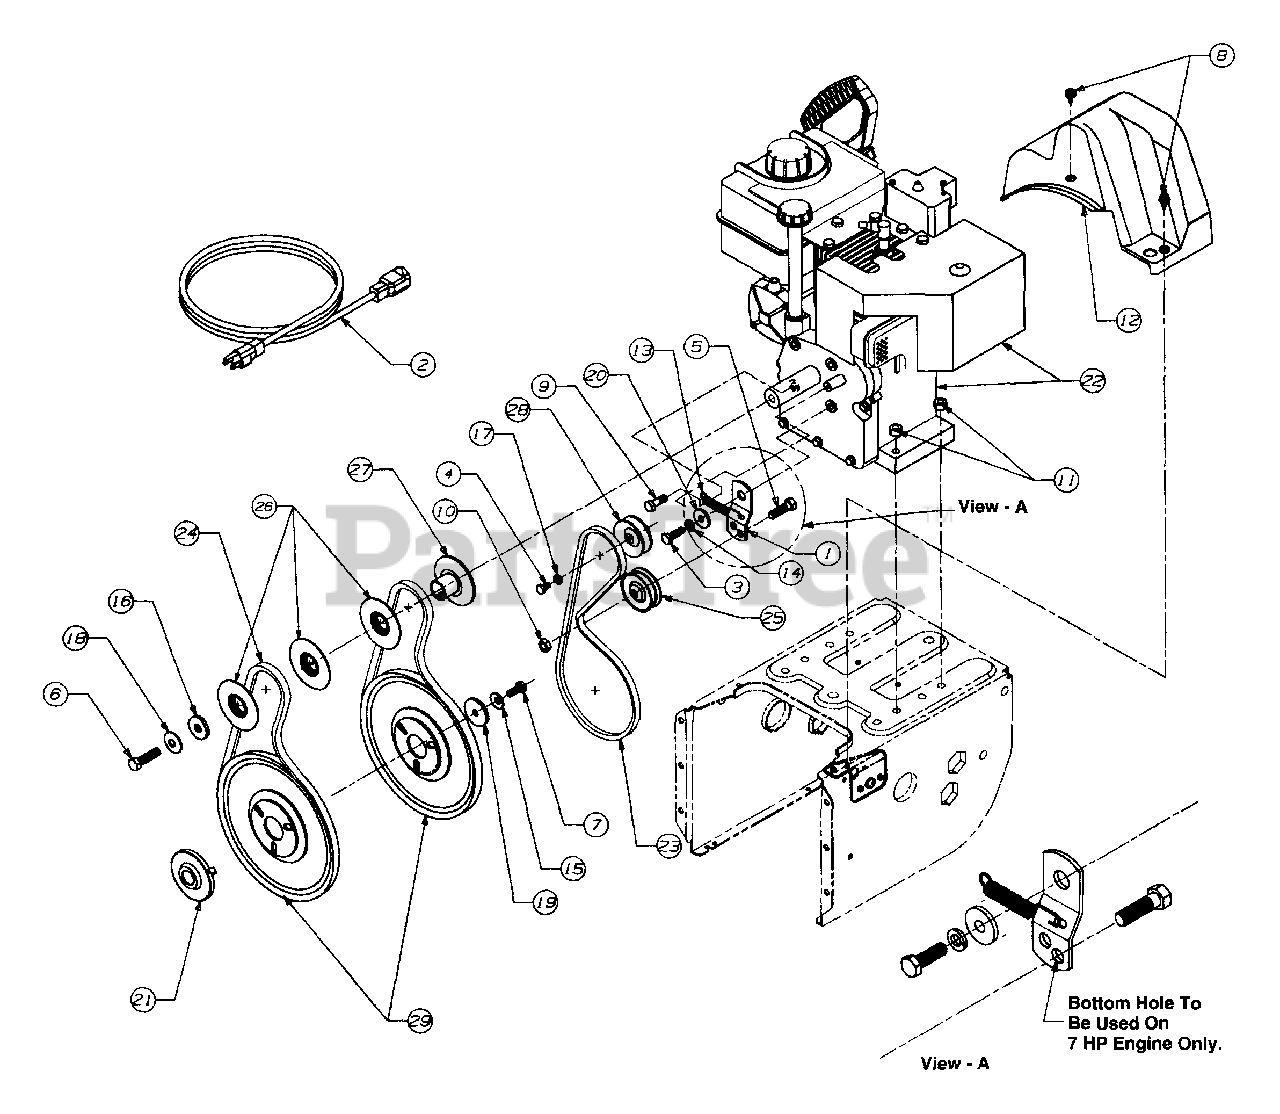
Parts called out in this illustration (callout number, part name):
3	Screw, Hex
4	Hex Screw
5	Screw, Hex
6	Hex Screw
7	Screw, Hex
8	Hex Screw
9	Screw, Hex
10	Hex Jam Nut
11	Nut, Hex
12	Belt, Cover
13	Spring
14	Lock Washer
15	Washer, Bell
16	Flat Washer
17	Washer, Lock
18	Washer, Lock
19	Washer, Flat
20	Shoulder Spacer
21	Pulley Adapter
22	Eng., HSK70 Tec. 7.0 HP Horz. w/Electric Starter
23	V-Belt
24	V-Belt Matched Set
25	Idler, Flat
26	Pulley, Half
27	Pulley, Half
28	Pulley
29	Pulley, Auger
